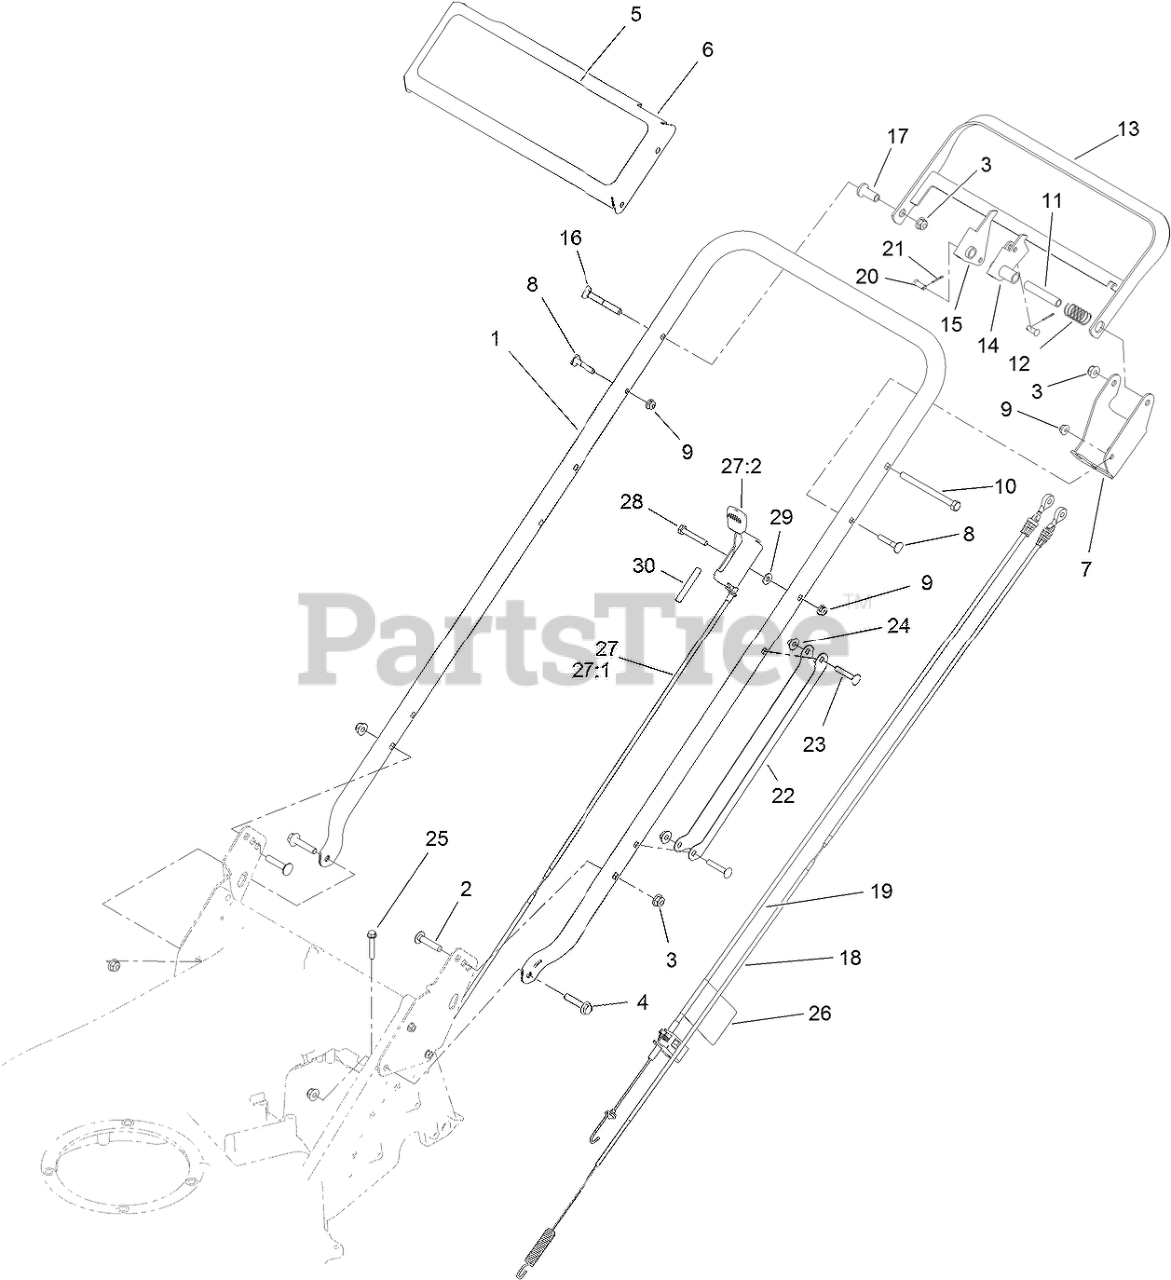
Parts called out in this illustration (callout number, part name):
1	HANDLE
2	BOLT-CARR
3	NUT-HF, NI
4	SCREW-HHF
5	DECAL-TORO, COMMERCIAL
6	PANEL-CONTROL
7	BRACKET-CONTROL
8	SCREW-HANDLE
9	NUT-HF
10	SCREW-HH
11	SPACER
12	SPRING-CONTROL
13	BAR-CONTROL
14	LEVER-CONTROL
15	LEVER-TRACTION
16	SCREW-HANDLE
17	SPACER-FLANGE
18	CABLE-BBC
19	CABLE-TRACTION, BBC
20	PIN-CABLE
21	PIN-COTTER
22	GUARD-CABLE, HANDLE
23	SCREW-CARR
24	NUT-HEX FLG
25	SCREW-HWH
26	DECAL-ADJUST, SELF PROPEL DRIVE
27	CONTROL-THROTTLE/CHOKE
27:1	CABLE-THROTTLE
27:2	CONTROL-THROTTLE
28	SCREW-HH
29	WASHER-FLAT
30	DECAL-THROTTLE, CHOKE
